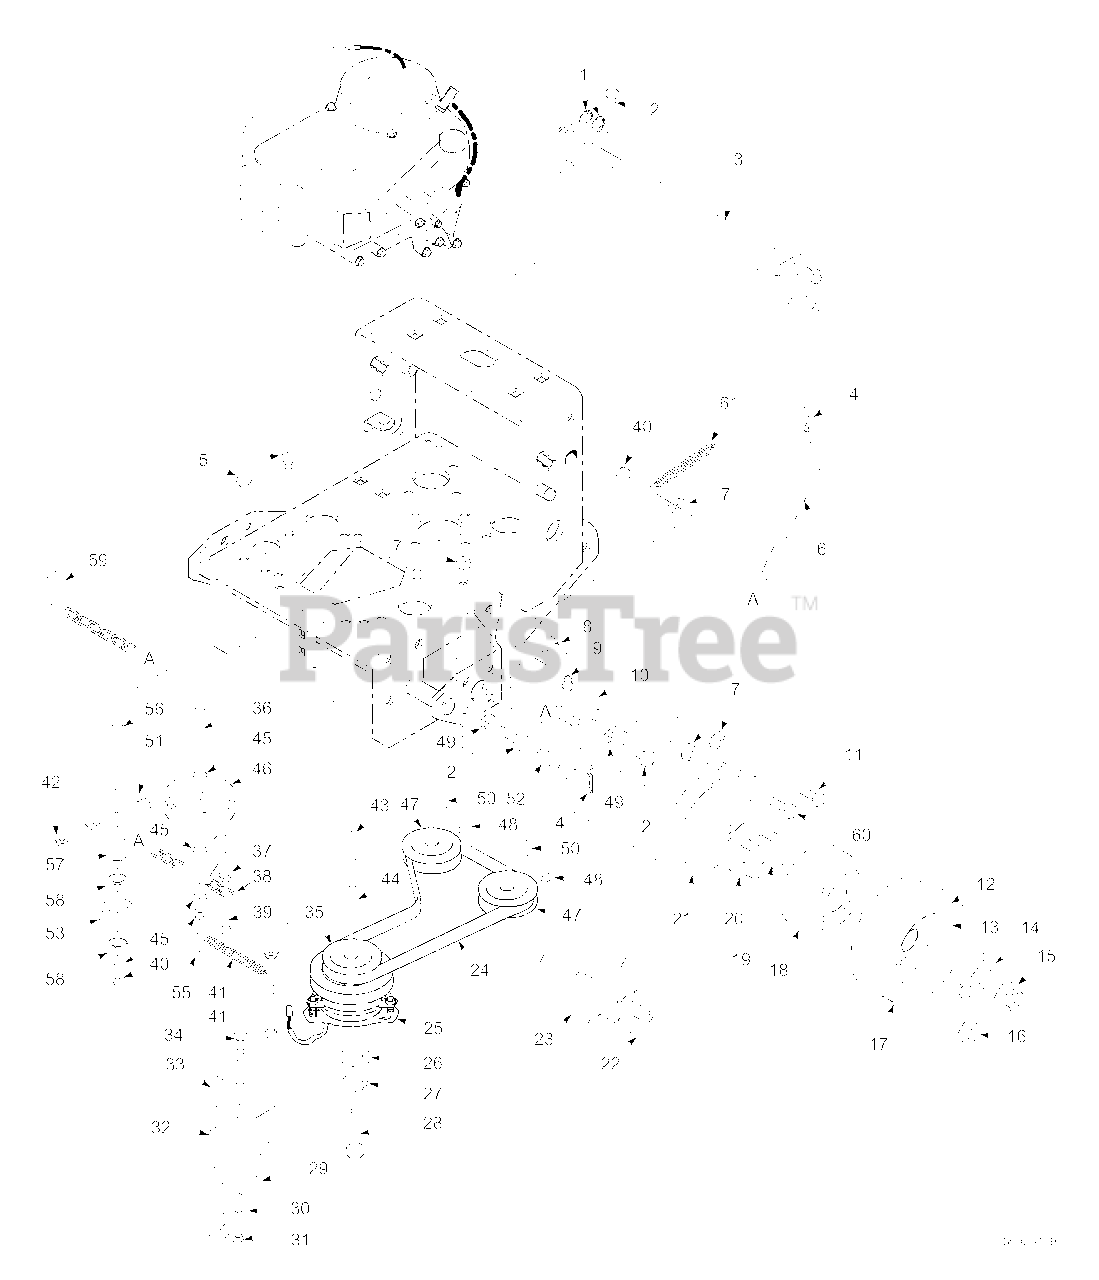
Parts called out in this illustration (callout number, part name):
1	Retaining Ring, 3/4" Ext. "E"
2	Bolt, Hex Head 3/8-16 x 1"
3	Brake Shaft Assembly Weldment
4	Hair Pin, Cotter (.094 x 1.62)
5	Bolt, Carriage 5/16-18 x .75"
6	Brake Rod, Lower
7	Nut, Hex Serrated Flange 3/8-16
8	Bushing, Brake
9	Grease Fitting
10	Brake Actuator Weldment, LH
11	Bolt, Hex Head 3/8-16 x 2.25"
12	Tire, 18 x 8.50-8, 4 Ply
13	Rim Assembly
14	Lockwasher, Wheel Motor
15	Nut, Hex Castle 3/4-28
16	Nut, Lug
17	Wheel Assembly (#12 tire mounted to #13 rim)
18	Brake Drum
19	1/2-20 Serrated Bolt
20	Hub,Wheel
21	Brake Band, 7.5"
22	Key, Woodruff 3/16 x .75"
23	Wheel Motor
24	Belt, Pump Drive
25	Electric Clutch
26	Flatwasher, 7/16" (.469 x 1.75 x .25)
27	Lockwasher, 7/16" Spring
28	Bolt, Hex Head M10-1.5 x 65mm
29	Plate, Backing
30	Clamp, Wire Loom
31	Nut, Hex Elastic Stop 5/16-18
32	Rubber Pad, Clutch Stop
33	Retainer, Clutch Stop
34	Bolt, Hex Head 5/16-18 x 1.75"
35	Pulley,Pump Drive-Engine
36	Bolt, Hex Head 3/8-16 x 2.75"
37	Nut, Hex Serrated Flange 1/4-20
38	Chain
39	Bolt, Hex Head 1/4-20 x 1.25"
40	Nut, Hex Elastic Stop 3/8-16
41	Spring, Pump Belt Idler
42	Nut, Hex Serrated Flange 5/16-18
43	Key, 1/4 x 1/4 x 2.75"
44	Key, 1/4 x 1/4 x 1"
45	Flatwasher, 3/8" (.391 x .938 x .105)
46	Pulley, Idler 4.5"
47	Pulley, Pump Shaft
48	Setscrew, 5/16-18 x 3/8"
49	Lockwasher, 3/8" Spring
50	Key, 5mm x 5mm x 25mm
51	Base, Idler Pivot
52	Swivel Joint
53	Idler Arm Weldment, Pump
55	Locknut, 3/8-16 Center Lock
56	Bolt, Hex Head 3/8-16 x 3"
57	Pivot, Idler (Long)
58	Ball Bearings
59	Ring, Split
60	Bolt, Hex Head 3/8-16 x 2.63"
61	Spring, Return
